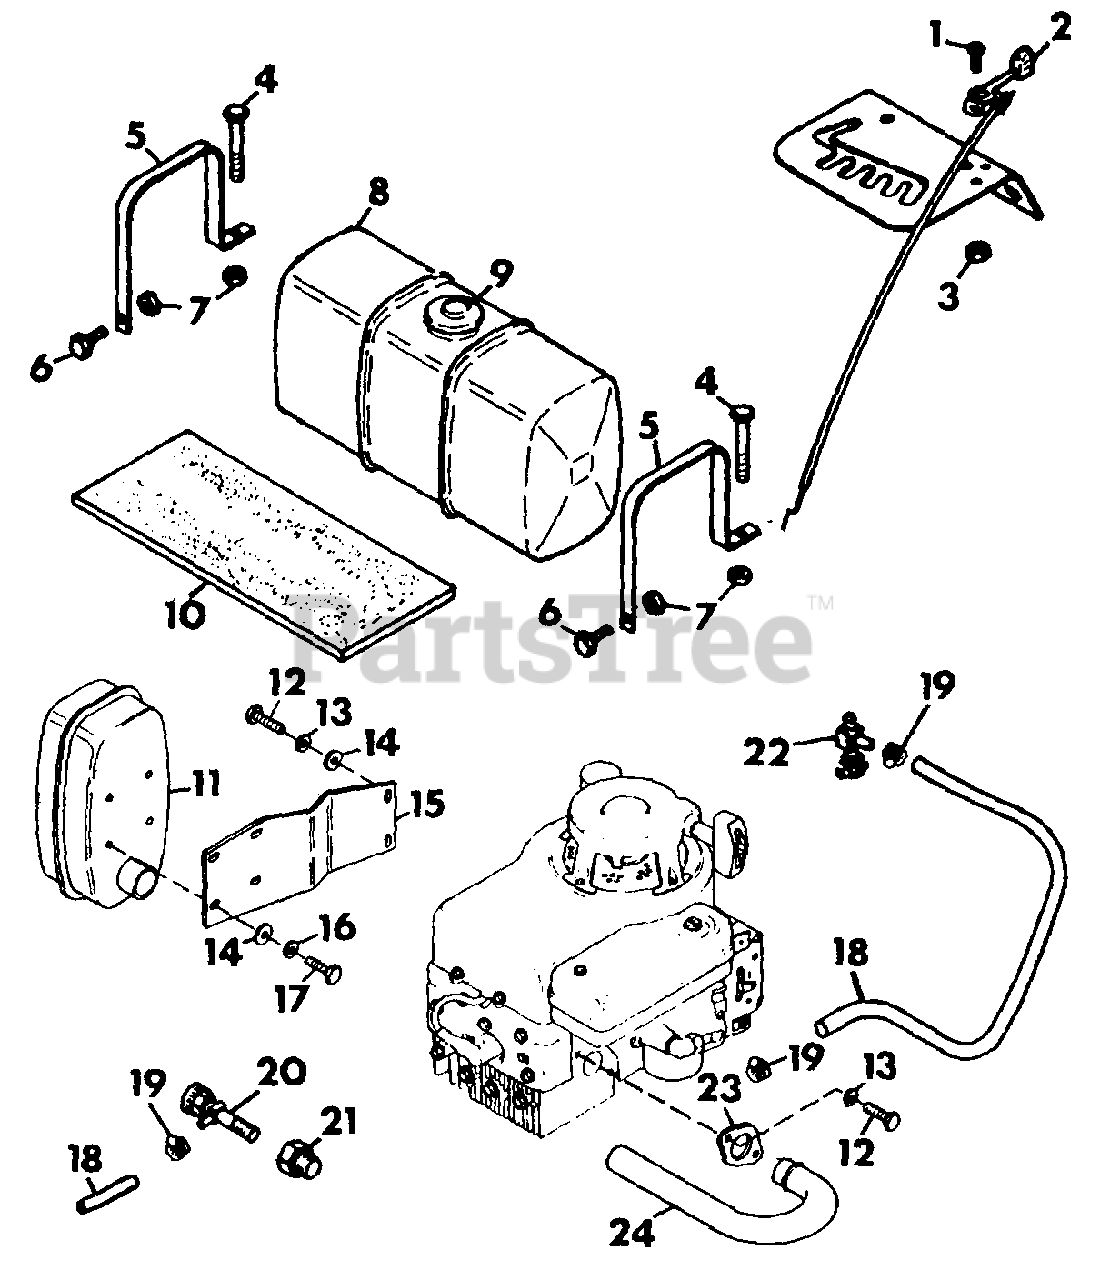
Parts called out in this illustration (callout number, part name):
1	SCREW, MACH. 10-24X.50 PHD
2	LEVER, THROTTLE CONTROL
3	NUT, LOCK 10-24
4	BOLT, HEX 1/4-20X1.75
5	STRAP, FUEL TANK
6	BOLT, HEX 1/4-20X.625
7	NUT, LOCK 1/4-20
8	TANK, FUEL (12 QTS.)
9	CAP, FUEL TANK
10	PAD, FUEL TANK
11	MUFFLER, 11 H.P. B & S
12	BOLT, HEX 5/16-18X.75
13	WASHER, LOCK 5/16 REG.
14	WASHER, FLAT .344X.688X.065
15	PLATE, EXHAUST
16	WASHER, LOCK 1/4 REG.
17	BOLT, HEX 1/4-20X.75
18	HOSE, FUEL
19	CLAMP, HOSE
20	COCK, OIL DRAIN
21	ADAPTOR, OIL DRAIN
22	VALVE AND STRAINER
23	FLANGE, MUFFLER
24	TUBE, EXHAUST
